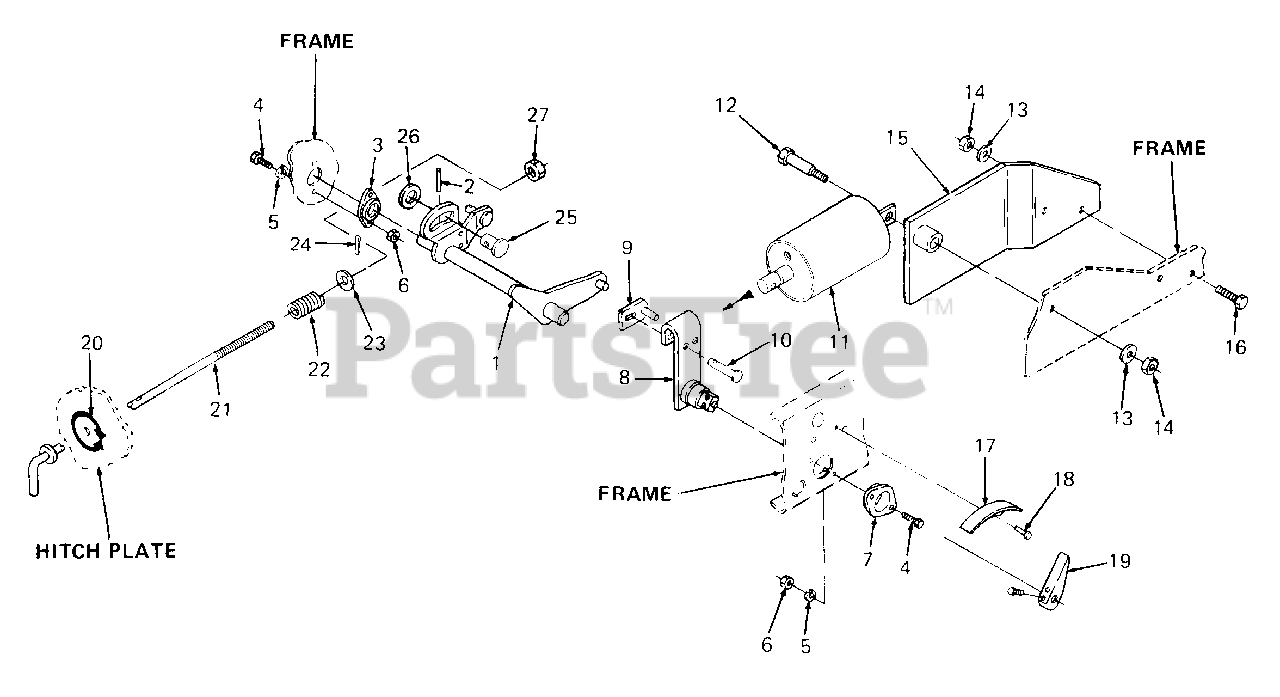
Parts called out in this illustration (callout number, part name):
3	Bushing, Lift, LH
4	Screw, Hex Cap, 1/4-20 X .75 Lg GR5
5	Washer, Lock, 1/4
6	Nut, Hex, 1/4-20 GR5
7	Bushing, Lift, RH
8	Bracket Assy, Lift
9	Pin Assy, Lift
10	Pin, Clevis, 1/2 Dia X 2.172 Lg
11	Cylinder, Hydraulic
12	Bolt, Shoulder
13	Washer, Flat, .531 X 1.06 X .134 Thk
14	Nut, Hex Center Lock, 1/2-13 GR5
15	Bracket, Cylinder
16	Screw, Hex Cap, 1/2-13 X 1.25 Lg GR5
17	Bracket, Height Indicator
18	Rivet, .156 Dia X .250 Lg
19	Indicator, Height
20	Graphic, Down Stop Adjustment
21	Rod, Down Stop Adjustment
22	Spring, Compression, .501 X .75 X 1.00 Lg
23	Washer, Flat, .656 X 1.312 X .074 Thk
24	Pin, Internal Cotter
25	Clevis, .750 X 1.00 Lg
26	Washer, Flat, .758 X 2.0 X .030 Thk
27	Nut, Hex LH Thrd, 1/4-28
